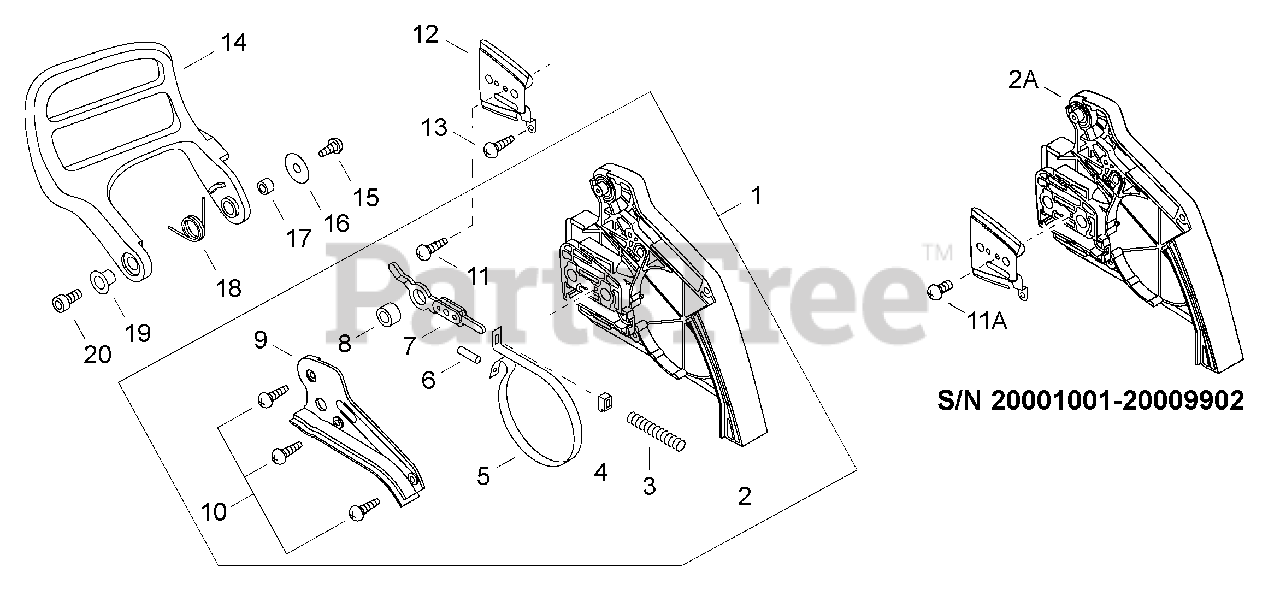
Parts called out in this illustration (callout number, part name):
1	BRAKE ASSY, CHAIN
2	GUARD, SPROCKET
2A	GUARD, SPROCKET
3	SPRING, COMPRESSION
5	BAND, BRAKE
6	PIN, SPRING 3x-9.8
7	CONNECTOR, BRAKE
8	SPACER 8×12×9
9	COVER, BRAKE
10	SCREW 4×12
11	SCREW 3×5
11A	SCREW 3×6
12	PLATE, GUIDE - OUTER
13	SCREW 4×12
14	LEVER, BRAKE
16	WASHER 4.2×16.5×1
17	SPACER 8×12×9
18	SPRING, TORSION
19	COLLAR 10
20	SCREW TAPPING 5×16
